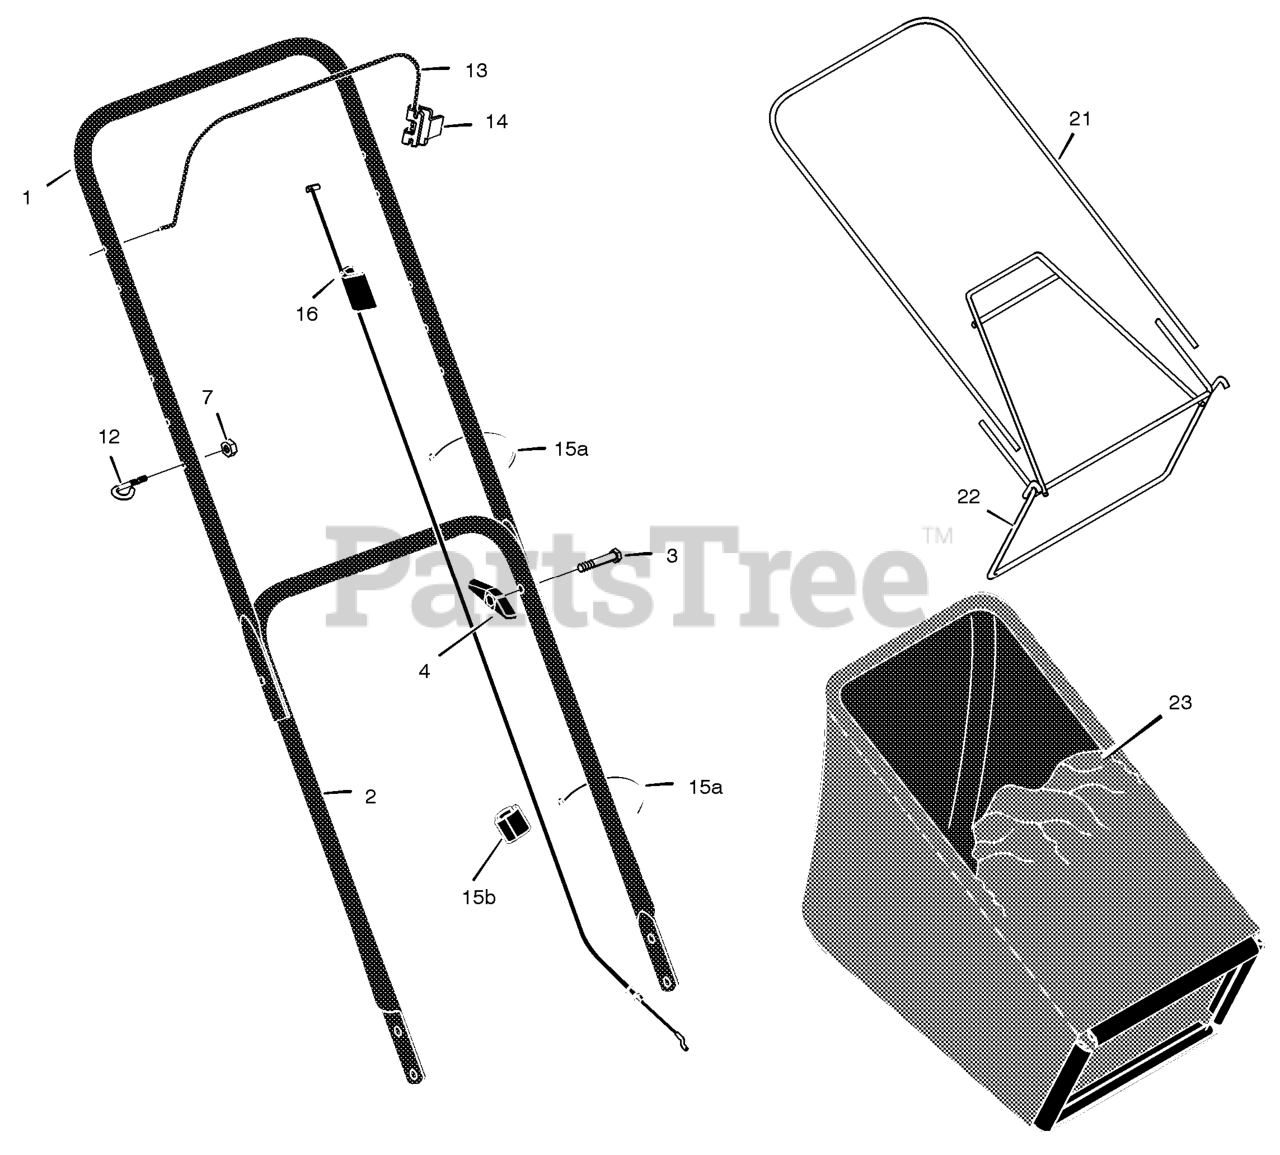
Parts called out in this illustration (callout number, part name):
1	Handle, Upper (Gray)
2	Handle, Lower (Gray)
4	Knob, Plastic
7	Locknut
12	Guide, Rope
13	Engine Stop Lever
14	Bracket, Stop Lever
15A	Tie, Cable
15B	Fastener, Single Cable
16	Engine Stop Cable
21	Frame, Top
22	Frame Assembly
23	Bag, Cloth
